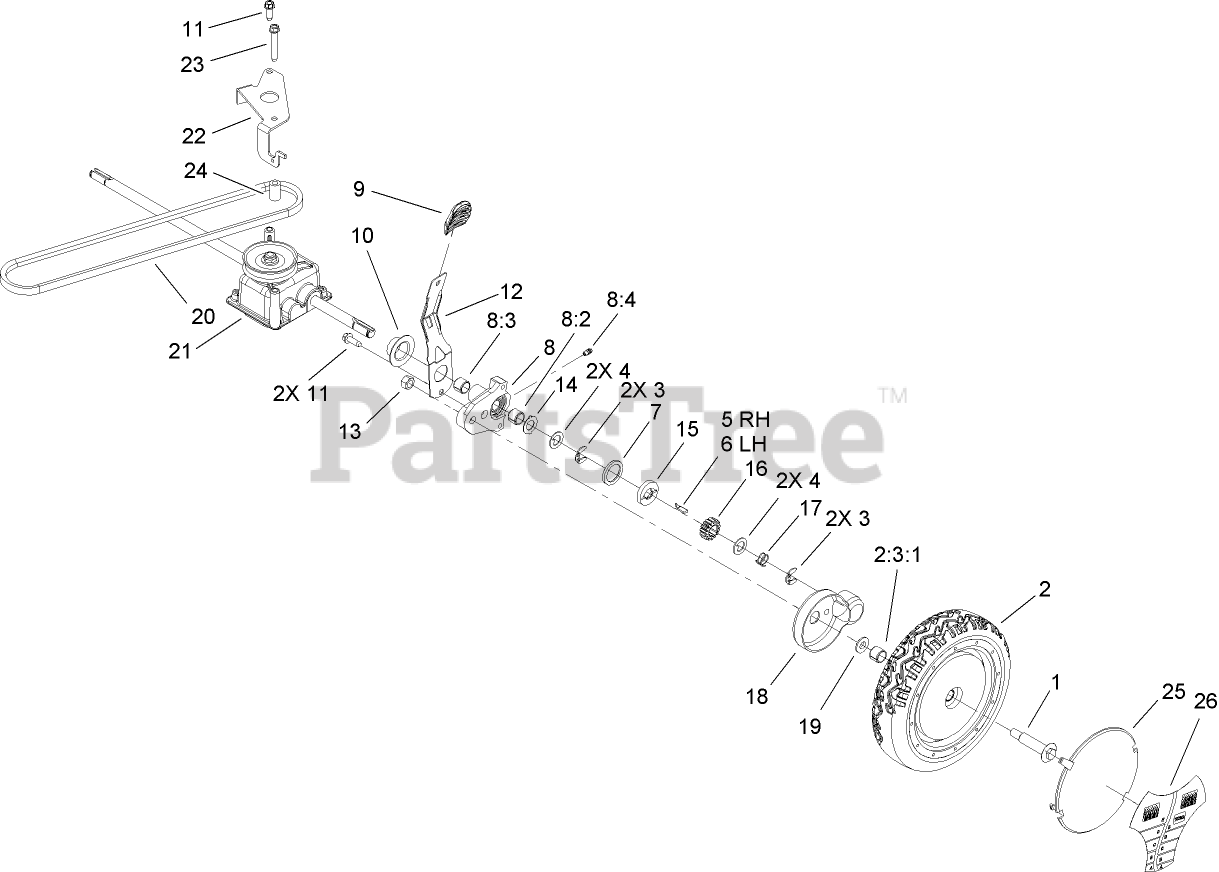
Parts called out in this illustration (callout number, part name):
1	BOLT-SHOULDER
2	8 INCH WHEEL AND GEAR ASM
2:3	Loose Parts Package
2:3:1	BUSHING
3	RING-RETAINING,CLIP
4	WASHER-THRUST, KEYED
5	KEY-ROCKING, RH
6	KEY-ROCKING, LH
7	RING-FRICTION
8	PIVOT ARM ASM
8:2	BUSHING
8:3	BUSHING
8:4	FITTING-GREASE
9	KNOB-LEVER, HOC
10	CAP-END
11	SCREW-HWHTF
12	ARM-SPRING
13	LOCKNUT
14	WASHER-ARM, PIVOT
15	WASHER-CLUTCH
16	GEAR-PINION
17	SPRING-COMPRESSION
18	COVER-WHEEL
19	SPACER-COVER, WHEEL
20	V-BELT
21	GEAR CASE ASM
22	BRACKET-GEARBOX
23	SCREW-HWHTF
24	BUSHING-PLATE, ACTUATOR
25	COVER-WHEEL
26	LABEL-WHEEL, SMART
